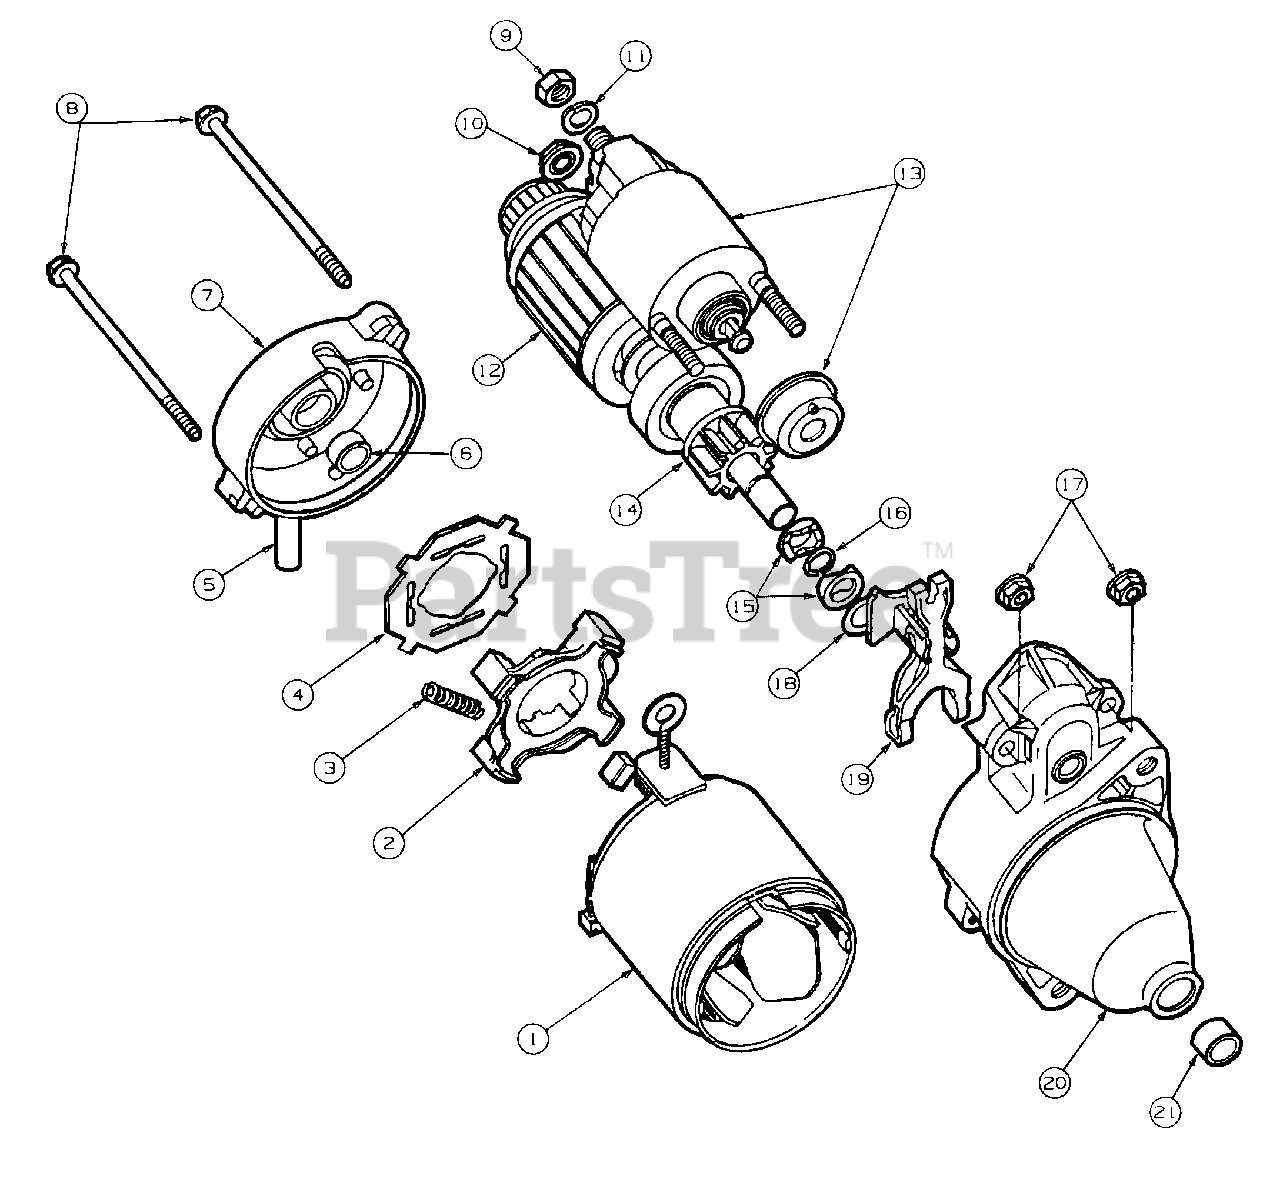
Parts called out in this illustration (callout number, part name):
1	Frame, Starter
2	Holder, Brush
3	Spring, Brush
6	Bearing, Oilless
7	Frame Assy, End
8	Bolt, Through
11	Washer, Spring
12	Armature, Starter
13	Switch, Magnetic
14	Clutch, Sub
15	Nut, Pinion Stop
18	Washer, Plate
19	Lever, Starter Drive
20	Housing, Starter
21	Bearing, Oilless
